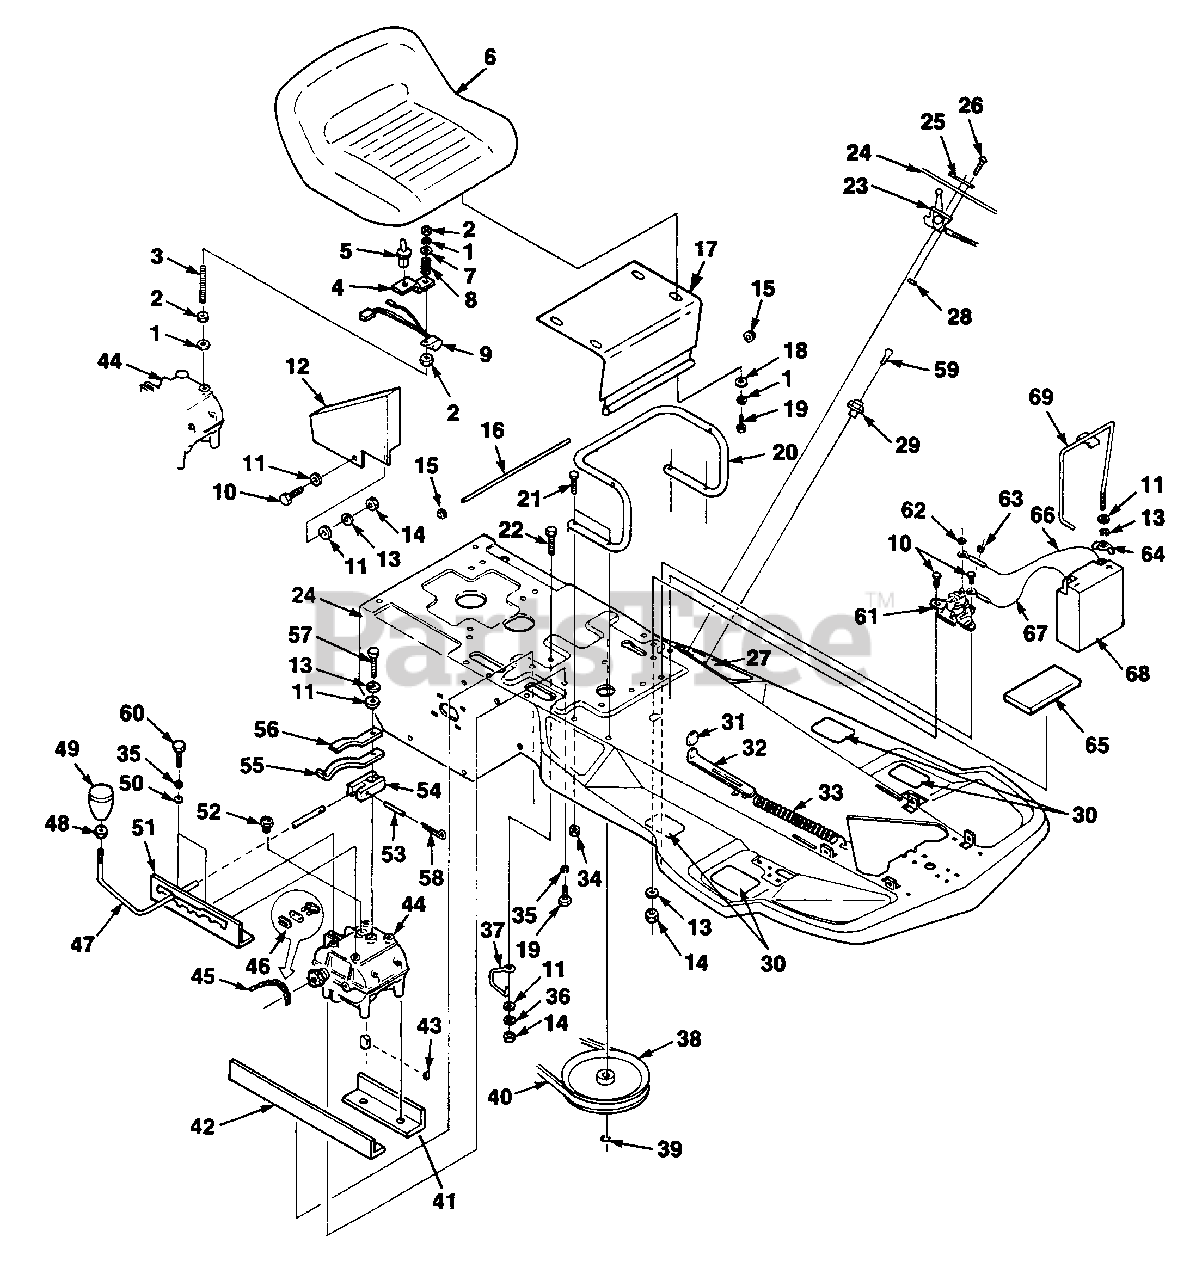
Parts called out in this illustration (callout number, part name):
1	WASHER- Lock 5/16"
2	NUT- Hex 5/16-18
3	STUD- 5/16-18
4	BRACKET- Transmission
5	SWITCH- Seat
7	RETAINER- Spring
8	SPRING- Compression
9	MODULE- Safety
10	SCREW- Hex centerlock 1/4-20 x 5/8"
11	WASHER- Plain 1/4"
12	GUARD- Chain
13	WASHER- Lock 1/4-20
14	NUT- Hex 1/4-20
15	NUT- Pal 5/16"
16	ROD- Seat
17	BRACKET- Seat
18	WASHER- Plain 5/16"
19	SCREW- Hex hd. 5/16-18 x 3/4"
20	SUPPORT- Seat
21	SCREW- Hex centerlock 1/4-20 x 1 1/2"
22	SCREW- Hex centerlock 1/4-20 x .825
23	CONTROL- Throttle
25	PLATE- Throttle
26	SCREW- Sems 10-24 x 1/2"
27	DECAL- Throttle
28	NUT- Hex 10-24
29	SWITCH- Ignition
30	PAD- Foot
31	KNOB- Tab
32	LATCH- Brake
33	SPRING- Extension
34	NUT- Hex centerlock 1/4-20
35	WASHER- Lock 5/16"
36	WASHER- Lock 1/4"
37	GUIDE- Belt
38	TRANSMISSION PULLEY
39	RING- Retaining
40	BELT- Transmission
41	ANGLE- Short
42	ANGLE- Long
43	KEY- Woodruff
44	TRANSMISSION
45	CHAIN #40
46	LINK- Connecting
47	LEVER- Gear
48	NUT- Hex jam 3/8-24
49	KNOB- Shift
50	WASHER- Plain 5/16"
51	LOCATOR- Gear
52	SWITCH- Neutral safety
53	PIN- Roll
54	BRACKET- Pivot
55	LEAF- Spring
56	LEAF- Spring
57	SCREW- Hex 1/4-20 x 7/8"
58	PIN- Cotter
59	KEY- Ignition
60	SCREW- Taptite 5/16-18 x 3/4"
61	SOLENOID
62	NUT- 1/4-20
63	NUT- 8-32
64	NUT- Wing
65	PAD- Battery
66	CABLE- Battery
67	CABLE- Battery ground
68	BATTERY
69	BRACKET- Battery
